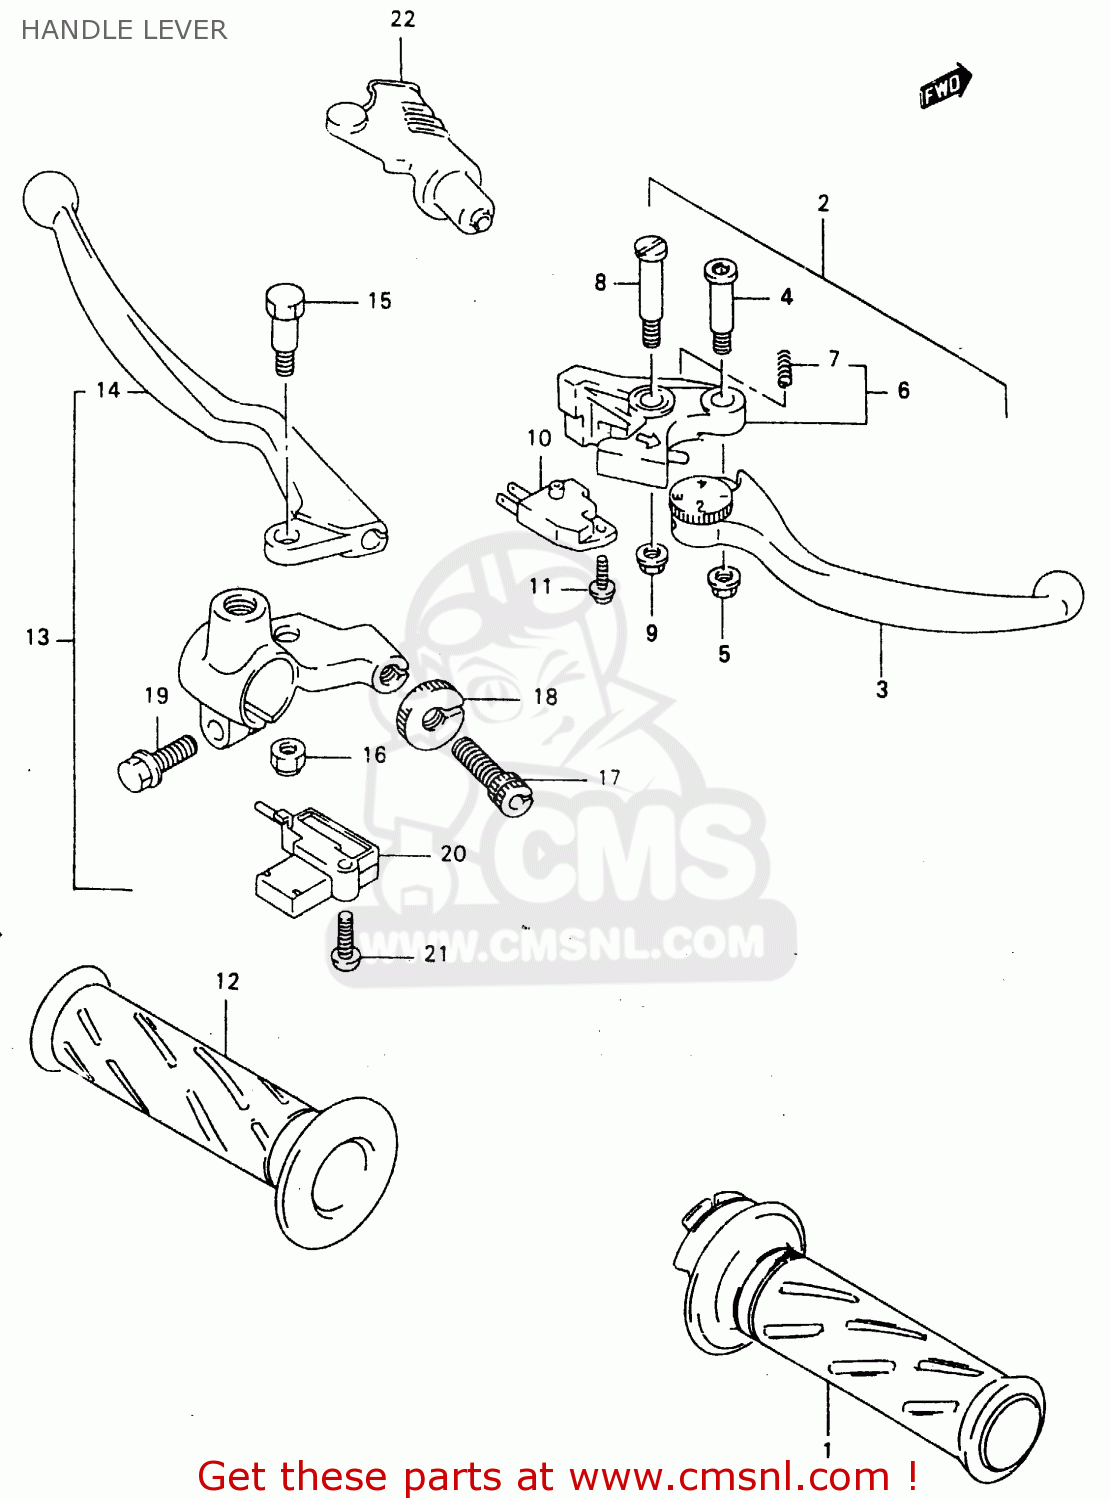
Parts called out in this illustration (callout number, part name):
1	GRIP,THROTTLE
2	LEVER ASSY,BRAKE
3	LEVER,ADJUST
4	BOLT,LEVER
5	NUT
6	KNOCKER
7	SPRING
8	BOLT,LEVER PIVOT
9	NUT
10	SWITCH ASSEMBLY,STOP
11	SCREW
12	GRIP,LEFT
13	LEVER ASSY,CLUTCH
14	LEVER,CLUTCH
15	BOLT,LEVER SET
16	NUT
17	ADJUSTER,WIRE
18	NUT,LOCK
19	SCREW
20	SWITCH,CLUTCH
21	SCREW
22	COVER,CLUTCH LEVER
